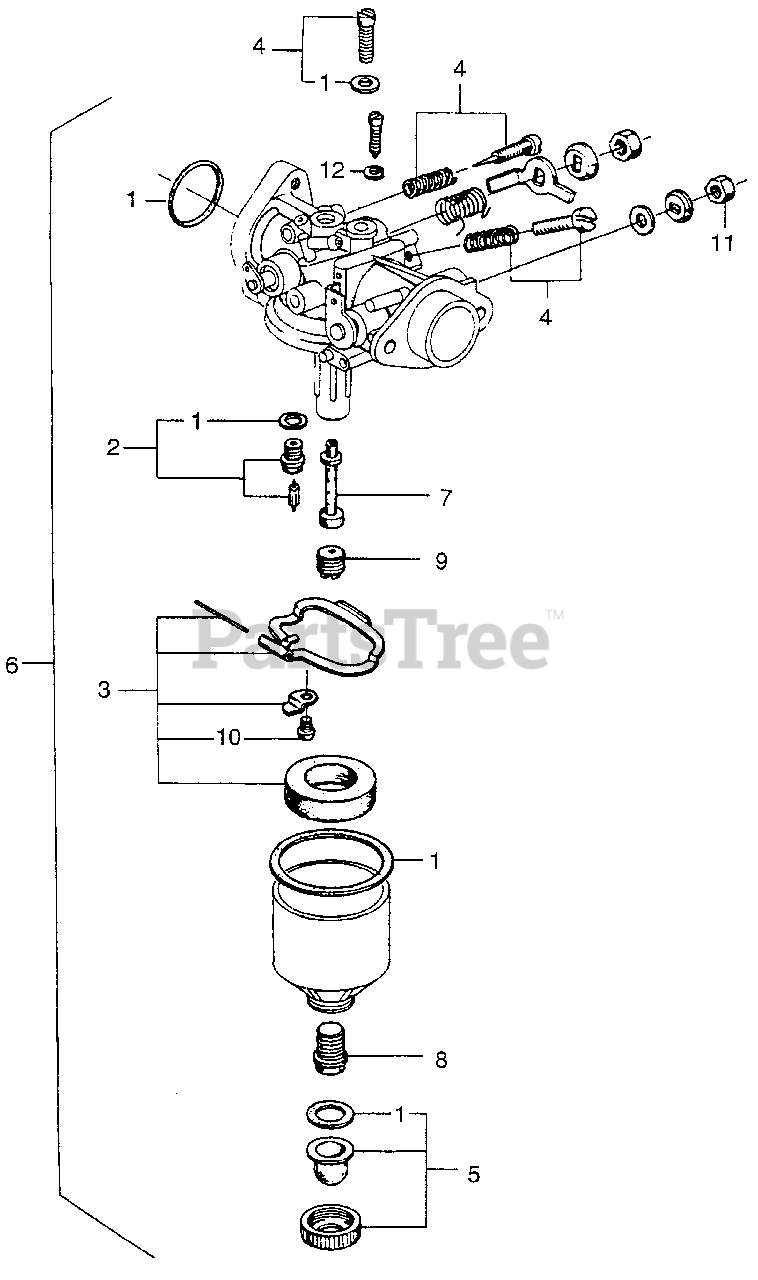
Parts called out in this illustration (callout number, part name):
1	GASKET SET
2	VALVE SET, FLOAT
3	FLOAT SET
4	SCREW SET A (NOT AVAILABLE)
5	CUP SET
6	CARBURETOR ASSY. (NOT AVAILABLE)
7	NOZZLE, MAIN (NOT AVAILABLE)
8	BOLT, HEX. (NOT AVAILABLE)
9	JET, MAIN (#65)
9	JET, MAIN (#65) Use from Engine SN 1007778.
9	JET, MAIN (#68)
9	JET, MAIN (#70)
9	JET, MAIN (#72)
9	JET, MAIN (#62)
10	SCREW, PAN (3X5)
11	NUT, HEX. (5MM)
12	WASHER, SPRING (3MM)
